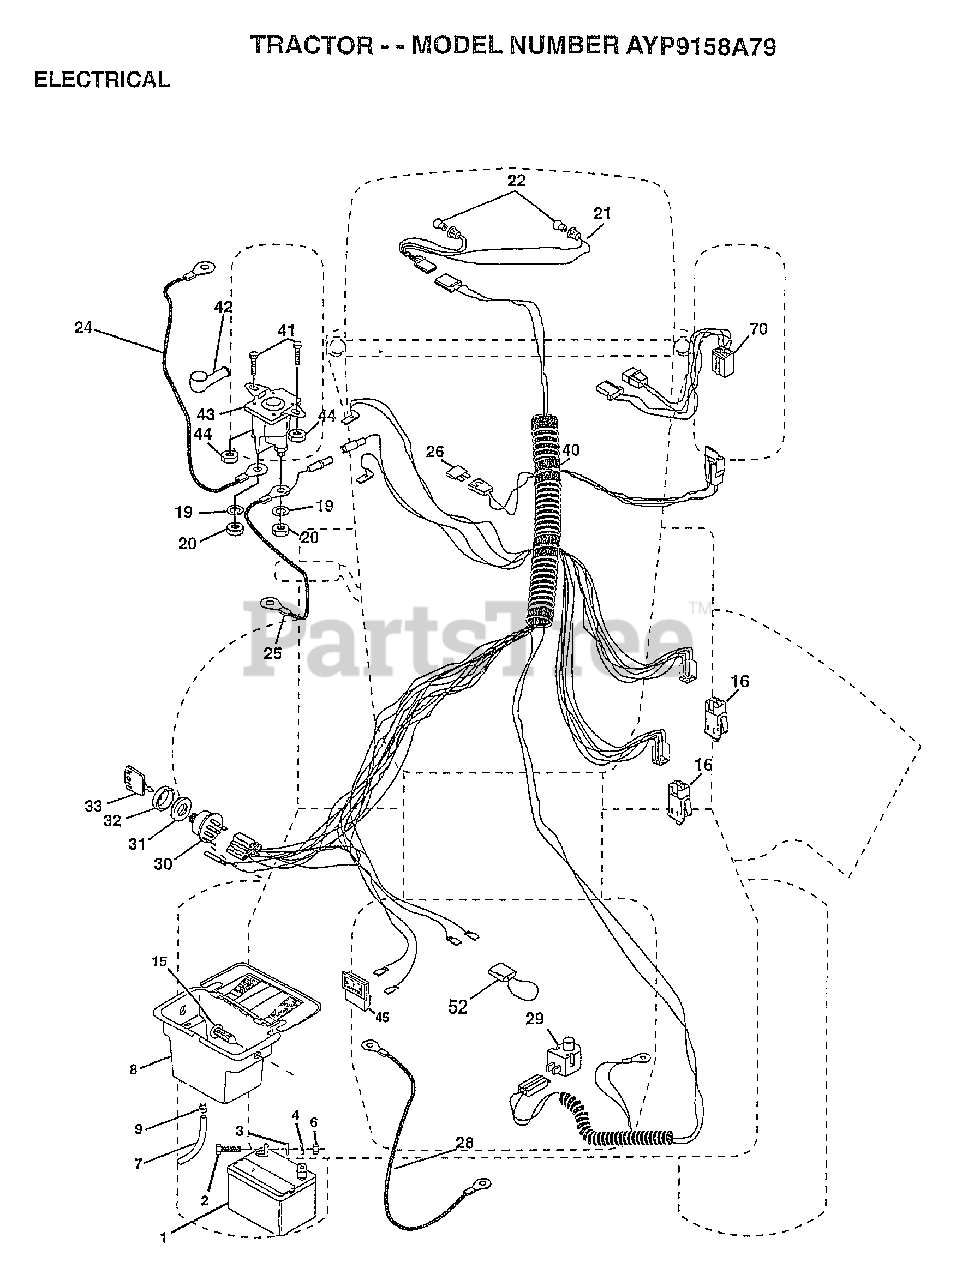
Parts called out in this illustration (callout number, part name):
2	BOLT LT
3	WASHER
4	LOCKWASHER
7	TUBE T
8	"CASE,BATTERY.MECH"
9	HOSE CLAMP T
15	FASTNER.SNAP-IN
16	SWITCH INTERLOCK
20	NUT
21	"HARNESS,LIGHT SOC"
22	HEADLAMP BULB
24	"CABLE T, BATTERY"
25	CABLE.BTRY.6GA.RD
26	FUSE HYT
28	CABLE T
29	SWITCH SEAT
30	SWITCH IGN 4POS
31	NUT IGNITION
32	COVER KEY SWITCH
33	KEY
40	HARNESS-IGNITION
41	BOLT HXHD FIN
44	NUT HXKEP 1/4X20
52	PROTECTION LOOP
70	HARNESS.ENG.DUAL
